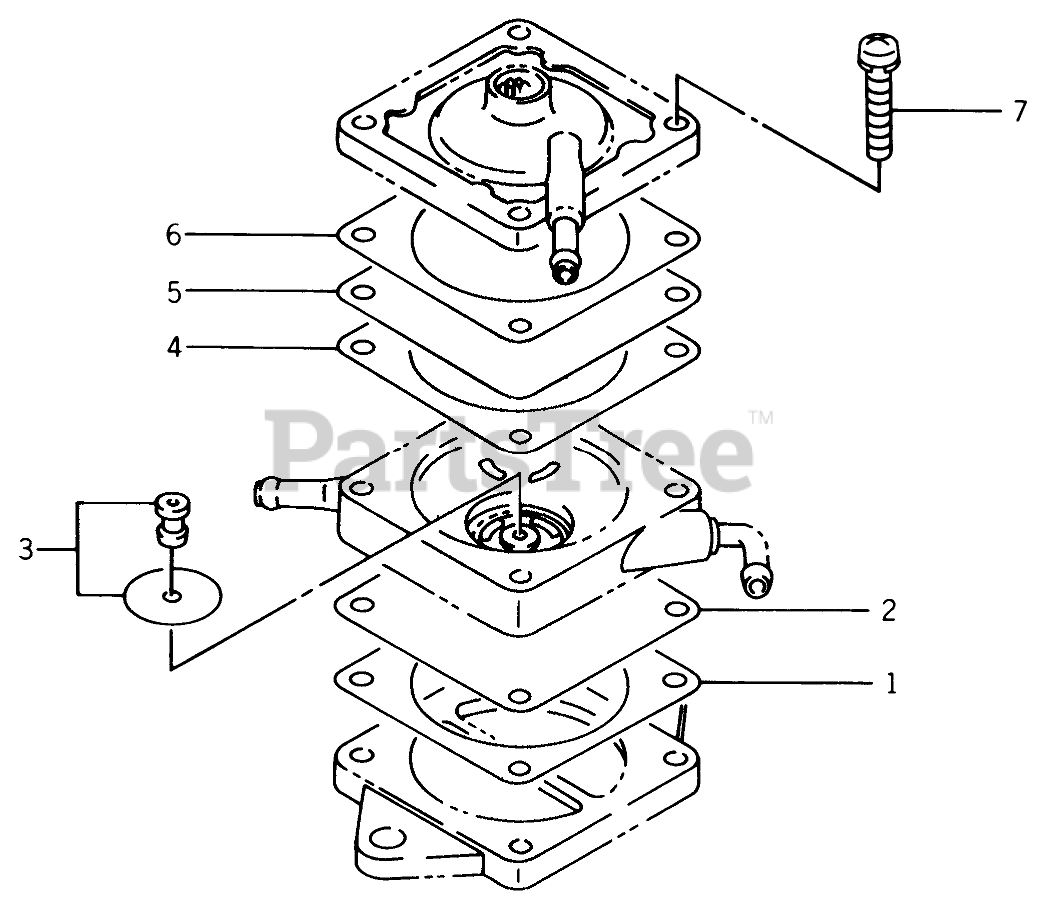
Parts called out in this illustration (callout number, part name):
1	GASKET
2	DIAPHRAGM
3	ASS'Y-VALVE
4	GASKET
5	DIAPHRAGM
6	GASKET
7	SCREW
